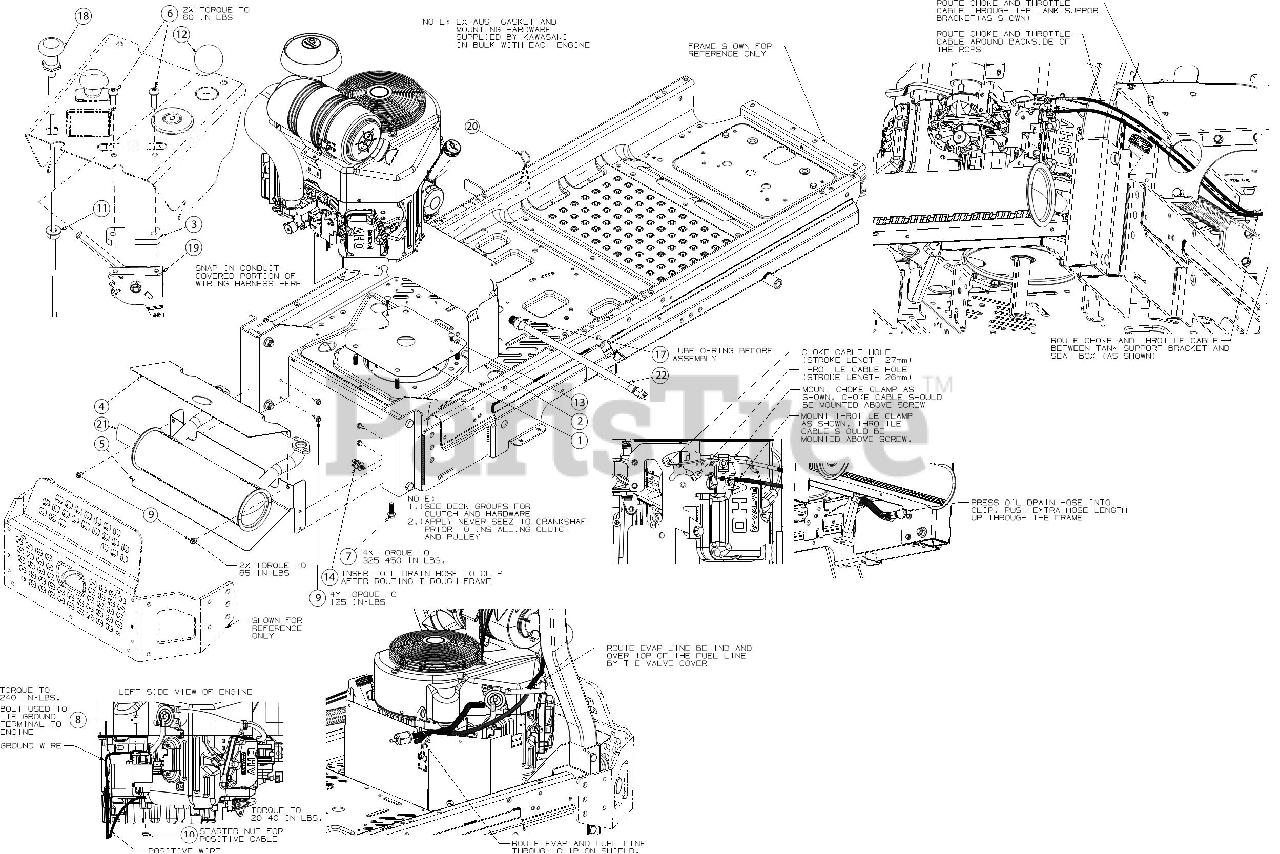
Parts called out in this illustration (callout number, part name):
1	ENGINE SHIELD PLATE
2	ENGINE SHIELD BRACKET
3	THROTTLE CABLE SPACER
4	MUFFLER SHIELD-TOP
5	MUFFLER SHIELD-BOTTOM
6	SCREW 1/4-20 x 1.0
7	SCREW 3/8-16 X1.250
8	SCREW M8-1.25 x 16 Gr8.8
9	SCREW 1/4-20X.625
10	FLANGE LOCK NUT
11	HEX FLANGE NUT
13	RATCHET CLIP .250
14	DRAIN HOSE CLIP
17	OIL DRAIN FITTING
18	40.5" CHOKE CABLE
19	THROTTLE CABLE 35.5"
20	TANK SUPPORT ROD
22	OIL DRAIN HOSE
